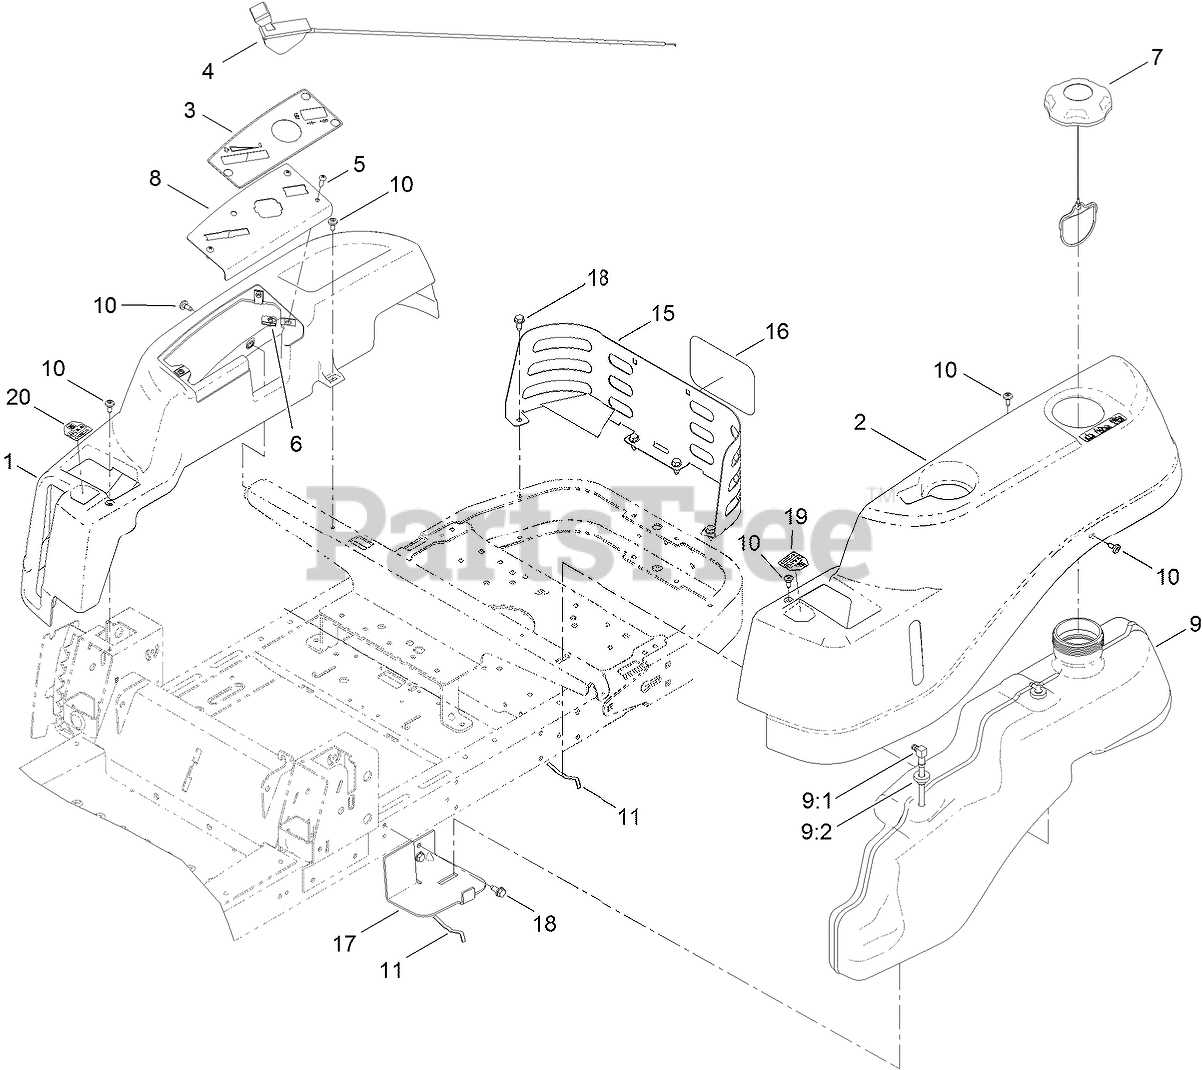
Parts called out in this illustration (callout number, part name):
1	POD-RH
2	POD-LH
3	DECAL-PANEL, CONTROL
4	CABLE-THROTTLE
5	SCREW-PRH
7	CAP-FUEL, RATCHETING
8	PLATE-CONTROL
9	FUEL TANK ASM
9:1	TUBE-DROP
9:2	BUSHING
10	SCREW-SHOULDER
11	SPRING
15	GUARD-REAR
17	SUPPORT-TANK, FRONT
18	SCREW-HWHTF
19	DECAL-CONTROL LEVER, LH
20	DECAL-CONTROL LEVER, RH
